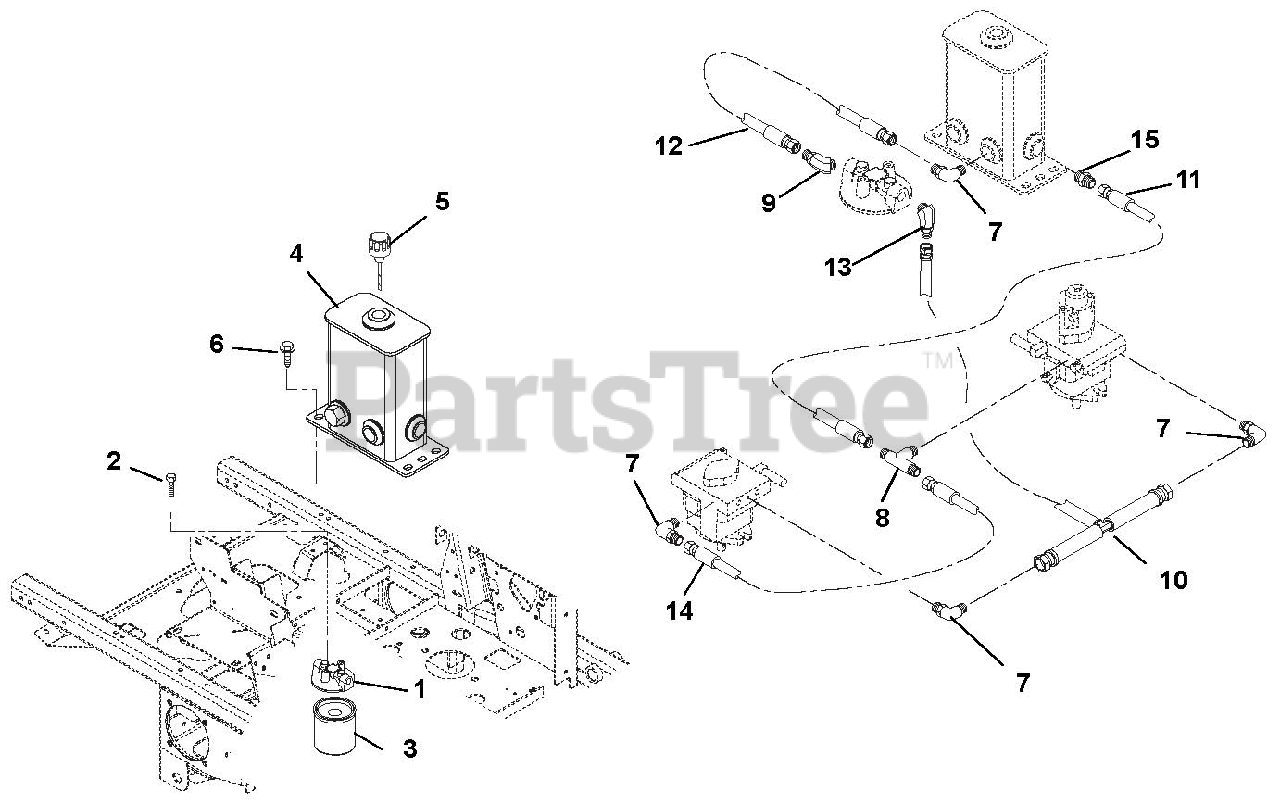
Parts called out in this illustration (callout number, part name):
1	Head, Filter
2	Bolt, Hex .25-20 x .50 Epoxy Grade 5
3	Oil Filter with Bypass
4	Weldment, Formed Hydraulic Tank – 2 Port
5	Dipstick, Breather, Steel 3"
6	Screw, Tapping Hex Washer Head .38-16 x .75
7	Fitting, Hydraulic, 90 Degree Elbow, Steel M8F – M80
8	Fitting, Hydraulic Tee M80 – M80 – M80
9	Fitting, Hydraulic Straight M80 – M80
10	Hose, Tee Assembly, .50
11	Hose, Hydraulic .50-19 – 0K FO8J0 – FO8J0
12	Hose, Hydraulic Molded
13	Fitting, Hydraulic 45° M80 – M80
14	Hose, Hydraulic
15	Adapter, Face Seal 8 x 8 .50 O-Ring 8 F5OLO – Steel
